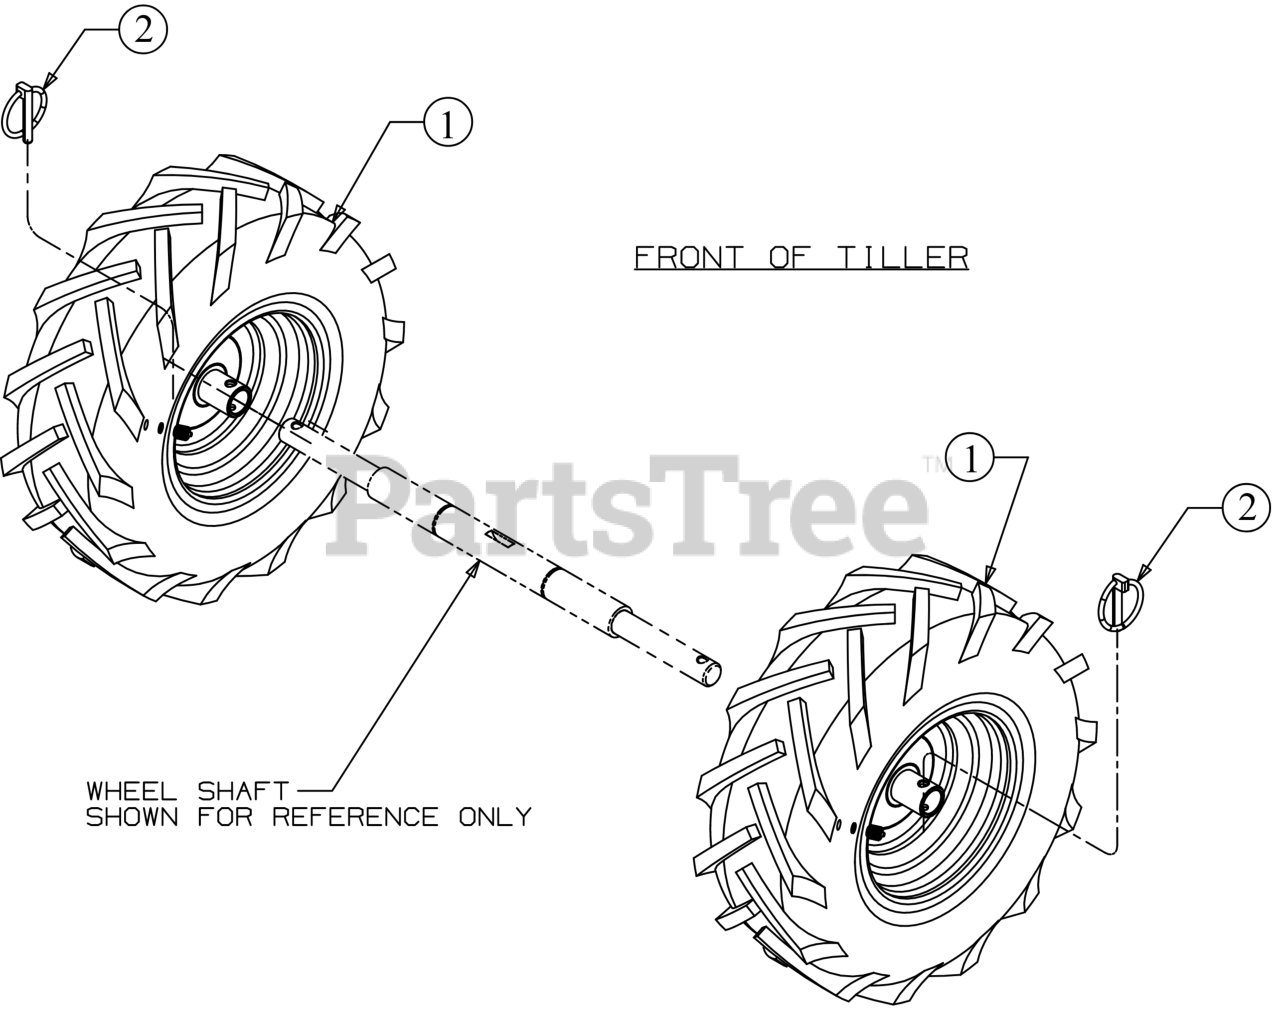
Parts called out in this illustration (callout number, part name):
1	WHEEL ASSEMBLY (13 X 5 X 6)
1	TUBELESS VALVE
1	TIRE 13 X 5.0 X 6.00
2	KLIK PIN
